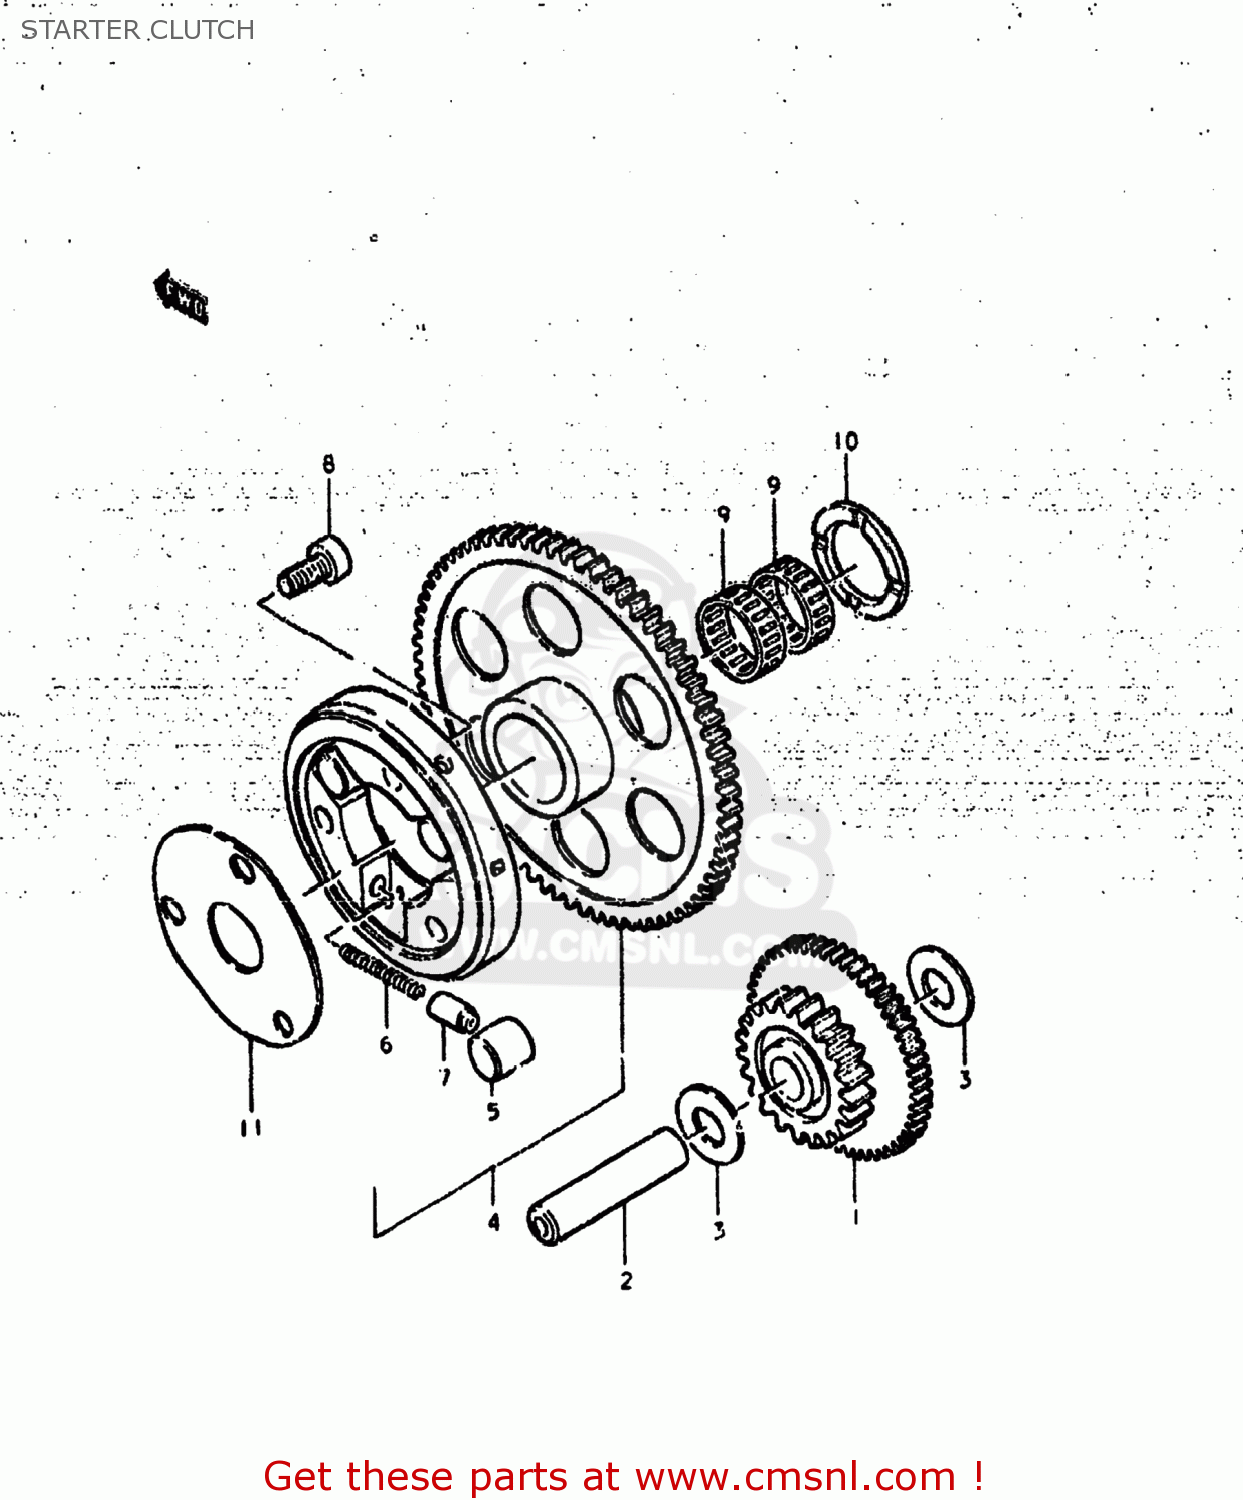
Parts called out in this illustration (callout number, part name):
1	GEAR,STARTER IDLER
2	PIN(7.4X13X56)
3	WASHER(13.3X25X0.85)
4	CLUTCH SET,STARTER
5	ROLLER(15X13)
6	SPRING
7	PIECE,PUSH
8	BOLT
9	BEARING(25X29X9.9)
10	WASHER(25X38X2.5)
11	SHIM,STARTER CLUTCH HUB
